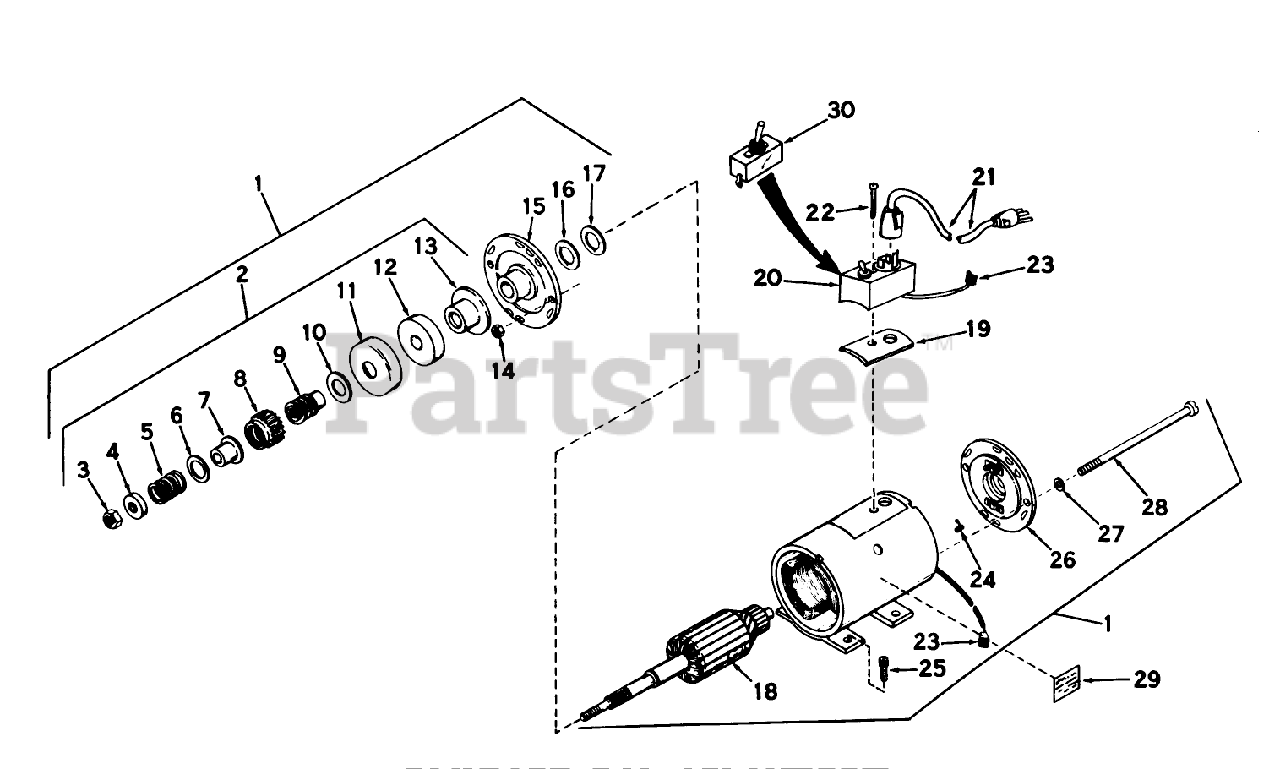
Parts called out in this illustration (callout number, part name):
1	Motor, Cranking (Incl. Nos. 2 thru 30)
2	Drive Assy., Complete (Incl. Nos. 1 thru 11)
3	Nut, Elastic stop
4	51084 3 1/2HP W/334
5	Spring, Anti-drift
6	Washer, Pinion
7	Sleeve, Anti-drift
8	Gear, Pinion
9	Shaft, Screw
10	Washer, Thrust
11	Cup, Cushion
12	Cushion, Rubber
13	Washer, Thrust
14	Nut, Securing
15	Cap Assy., Drive end (Incl. bearing)
16	Washer, Spacing (.005 thick)(Use as required)
16	Washer, Spacing (.010 thick)(Use as required)
16	Washer, Spacing (.02 thick)(Use as required)
17	Washer, Nylon
18	Armature
19	Setscrew
20	Rectifier Assy. (Incl. 2 of each of Nos. 23 24; 1 of No.30)
21	Cord, Extension (10-)
22	Screw, Sems
23	Brush Spring Kit (Incl. 2 of No. 24)
24	Spring, Brush
25	Screw
26	Cap Assy., Commutator end
27	Washer, Lock
28	Bolt, Thru
29	Decal, Caution
30	Switch, Toggle
